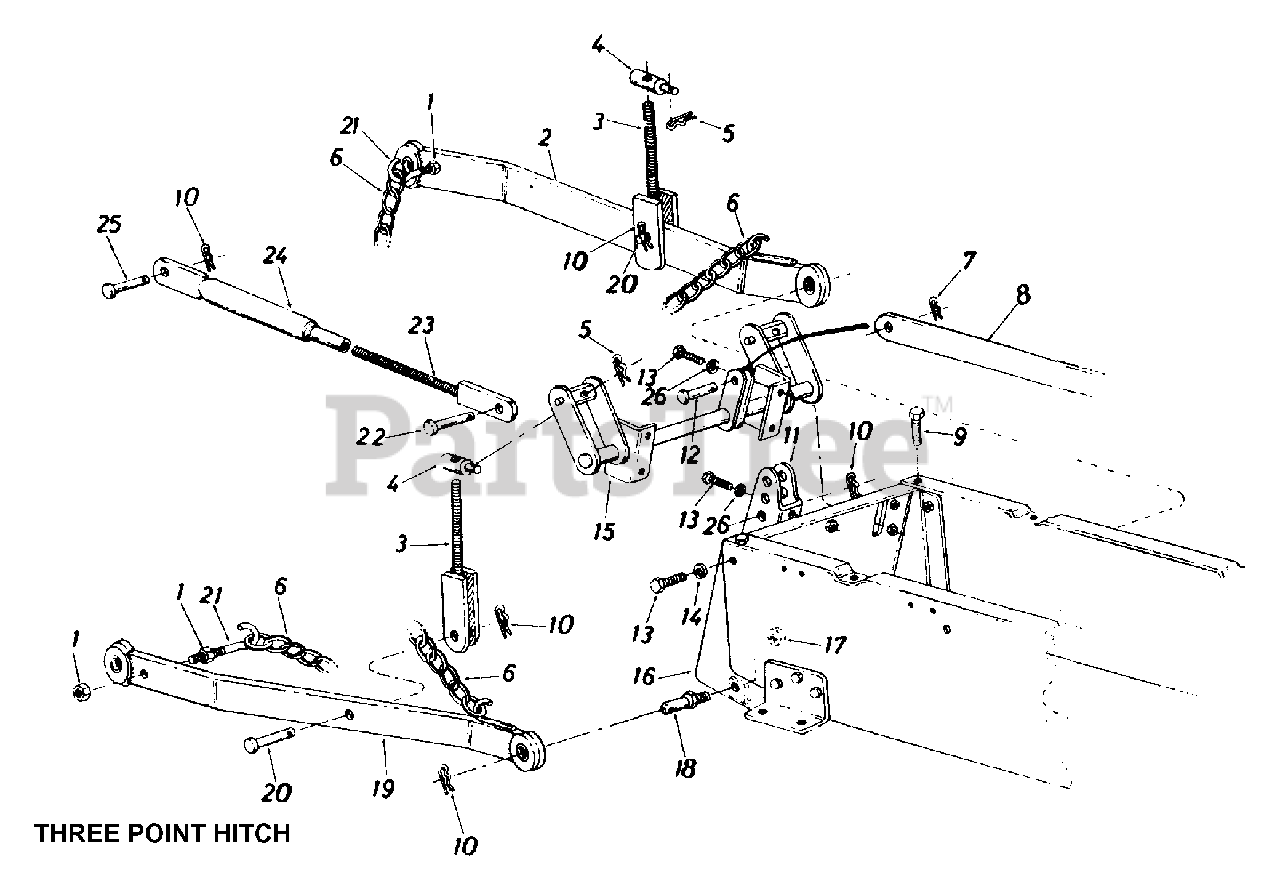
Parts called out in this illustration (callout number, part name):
1	Hex Cent. L-Nut 7/16-14 Thd.
5	Hitch Pin Clip
6	Chain - 20 Links
7	Cotter Pin 1/8" Dia. x 1.25" Lg.
10	Hairpin Cotter
13	Hex Scr. 3/8-16 x .75" Lg.
14	L-Wash. 3/8" Scr. - H.D.
18	Link Clevis Pin
21	Hitch Chain Hook
22	Clevis Pin .63" Dia. x 2.4" Lg.
23	Clevis Screw
25	Clevis Pin .63" Dia. x 2.4" Lg.
26	L-Wash. 3/8" Scr. - H.D.
